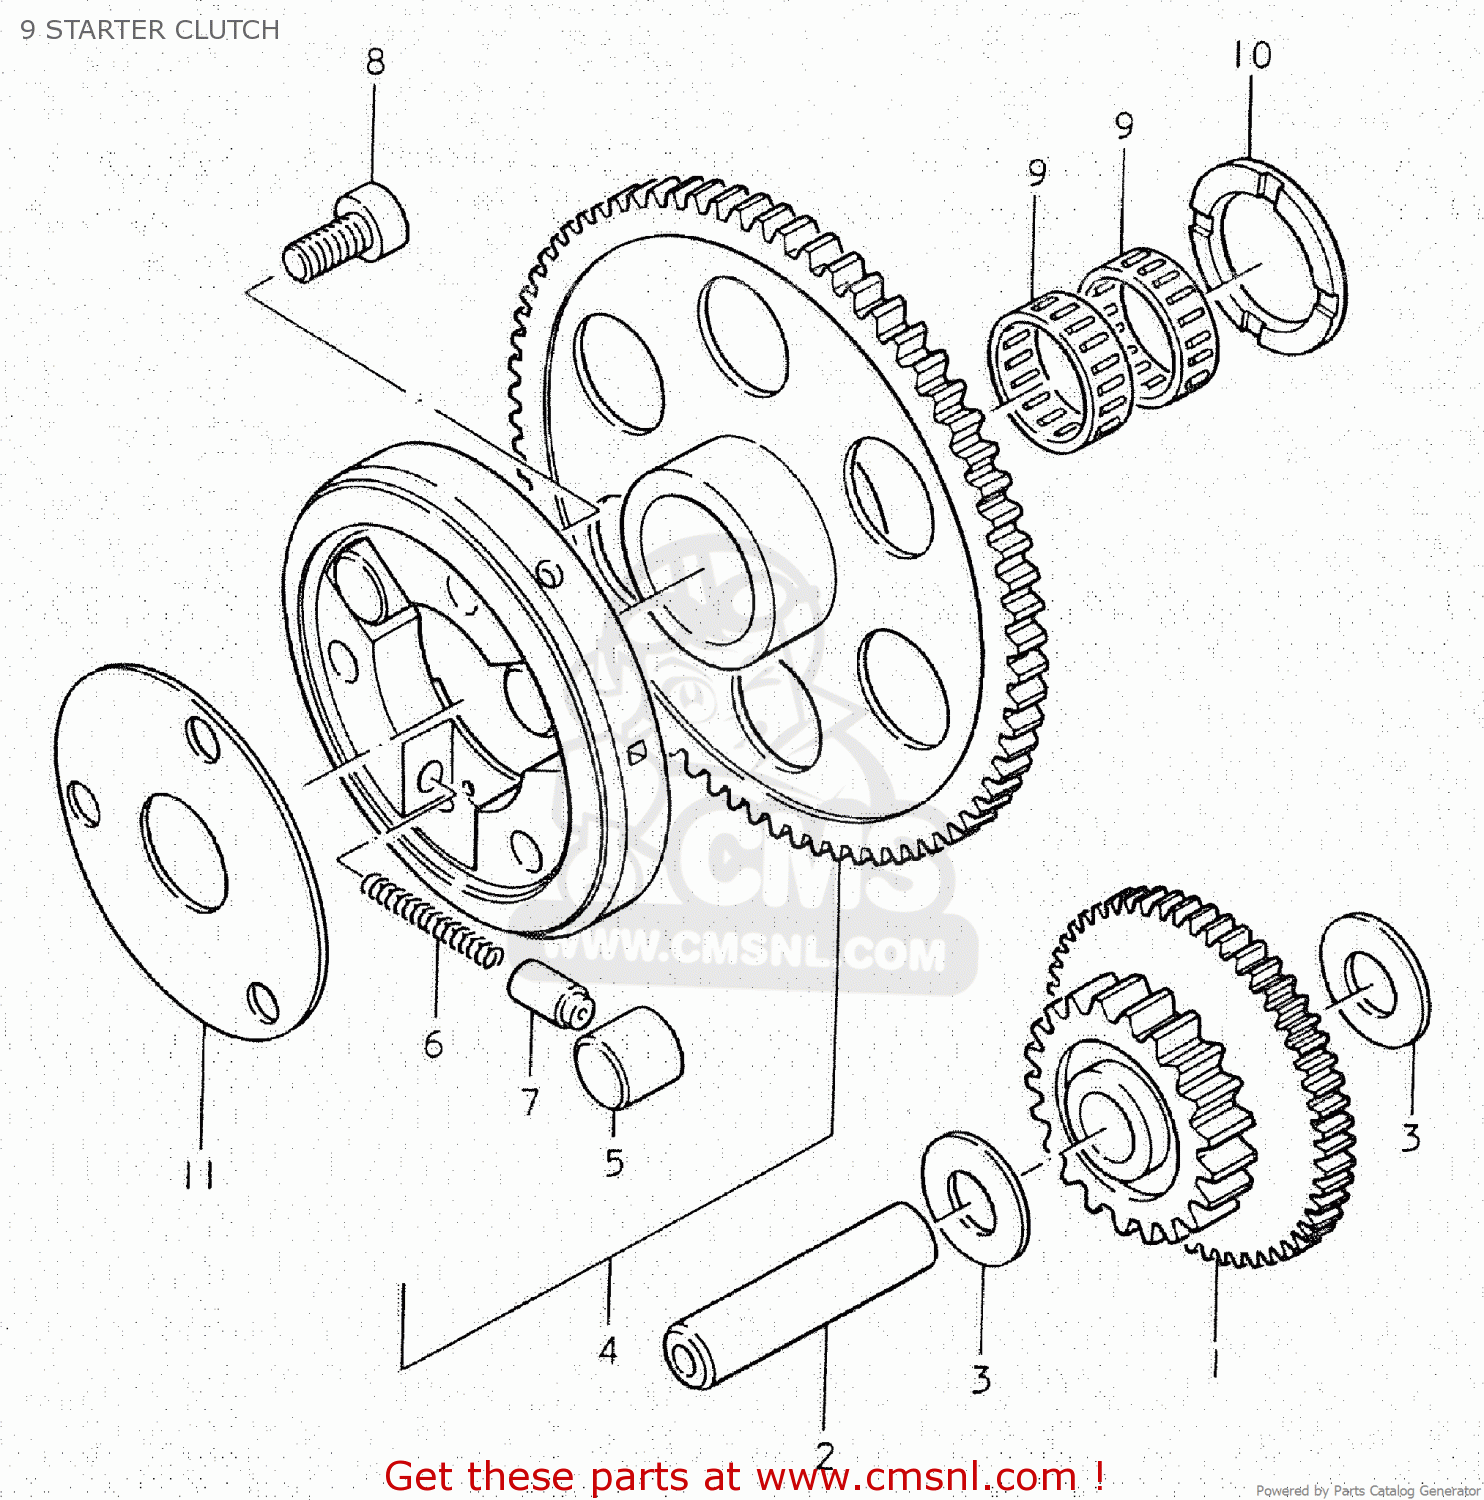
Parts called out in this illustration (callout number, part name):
1	GEAR,STARTER IDLE
2	PIN(7.4X13X56)
3	WASHER(13.3X25X0.85)
4	CLUTCH SET,STARTER
5	ROLLER(15X13)
6	SPRING
7	PIECE,PUSH
8	BOLT
9	BEARING(25X29X9.9)
10	WASHER(25X38X2.5)
11	SHIM,STARTER CLUTCH HUB
